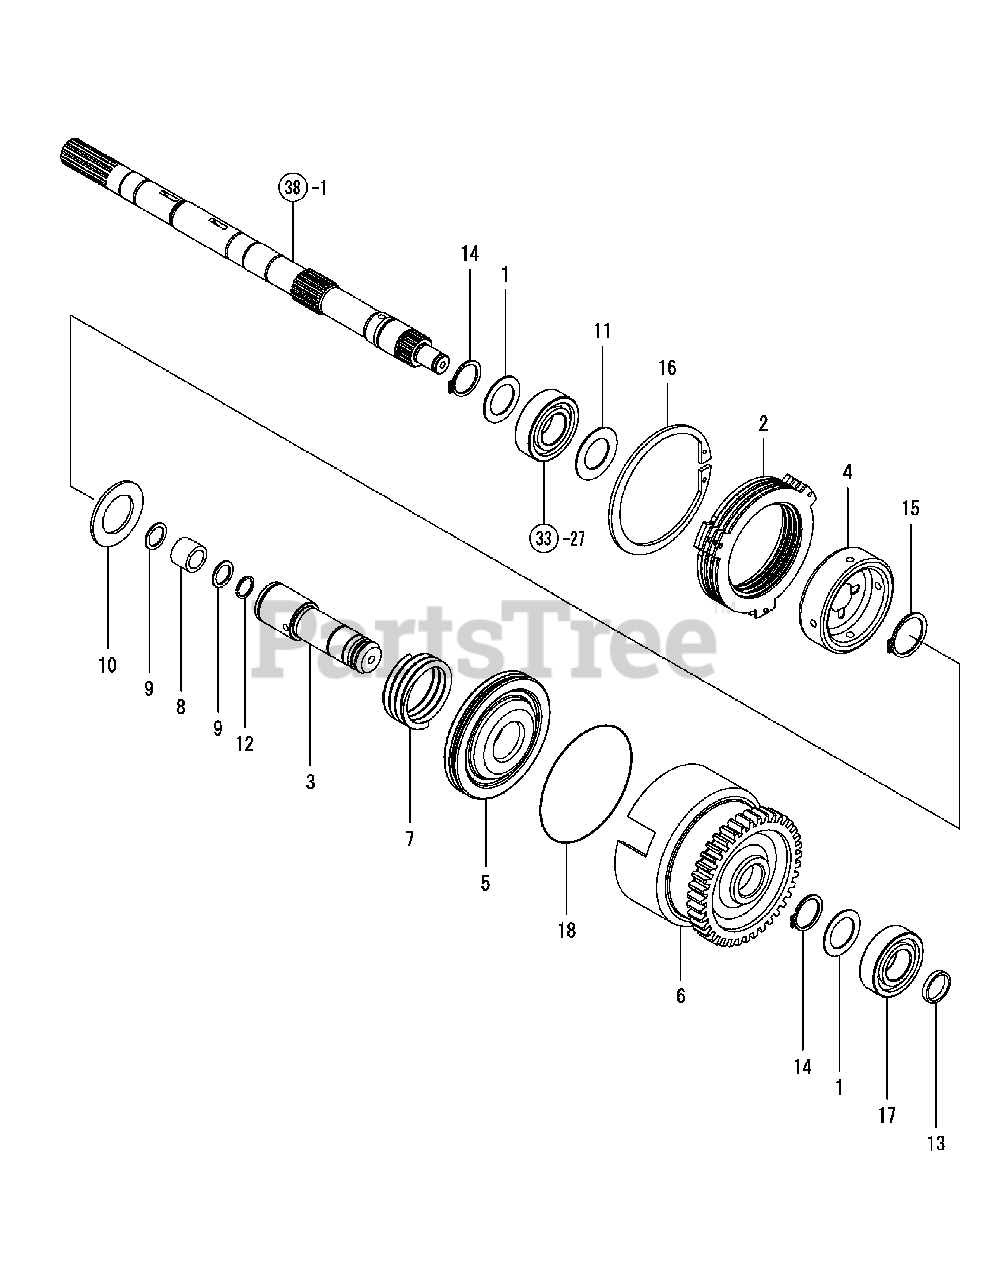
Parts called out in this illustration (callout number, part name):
2	DISC KIT, FRICTION
4	COLLAR, SPLINE
6	GEAR, CLUTCH Z=39
7	SPRING, PTO RETURN
8	NEEDLE, 121718
9	WASHER, 13X17X1
10	WASHER 25X42X2
11	WASHER, 20X34X1
13	RING, SEAL 17203
17	BALL BEARING #6004
18	O-RING 1A G-75.0
